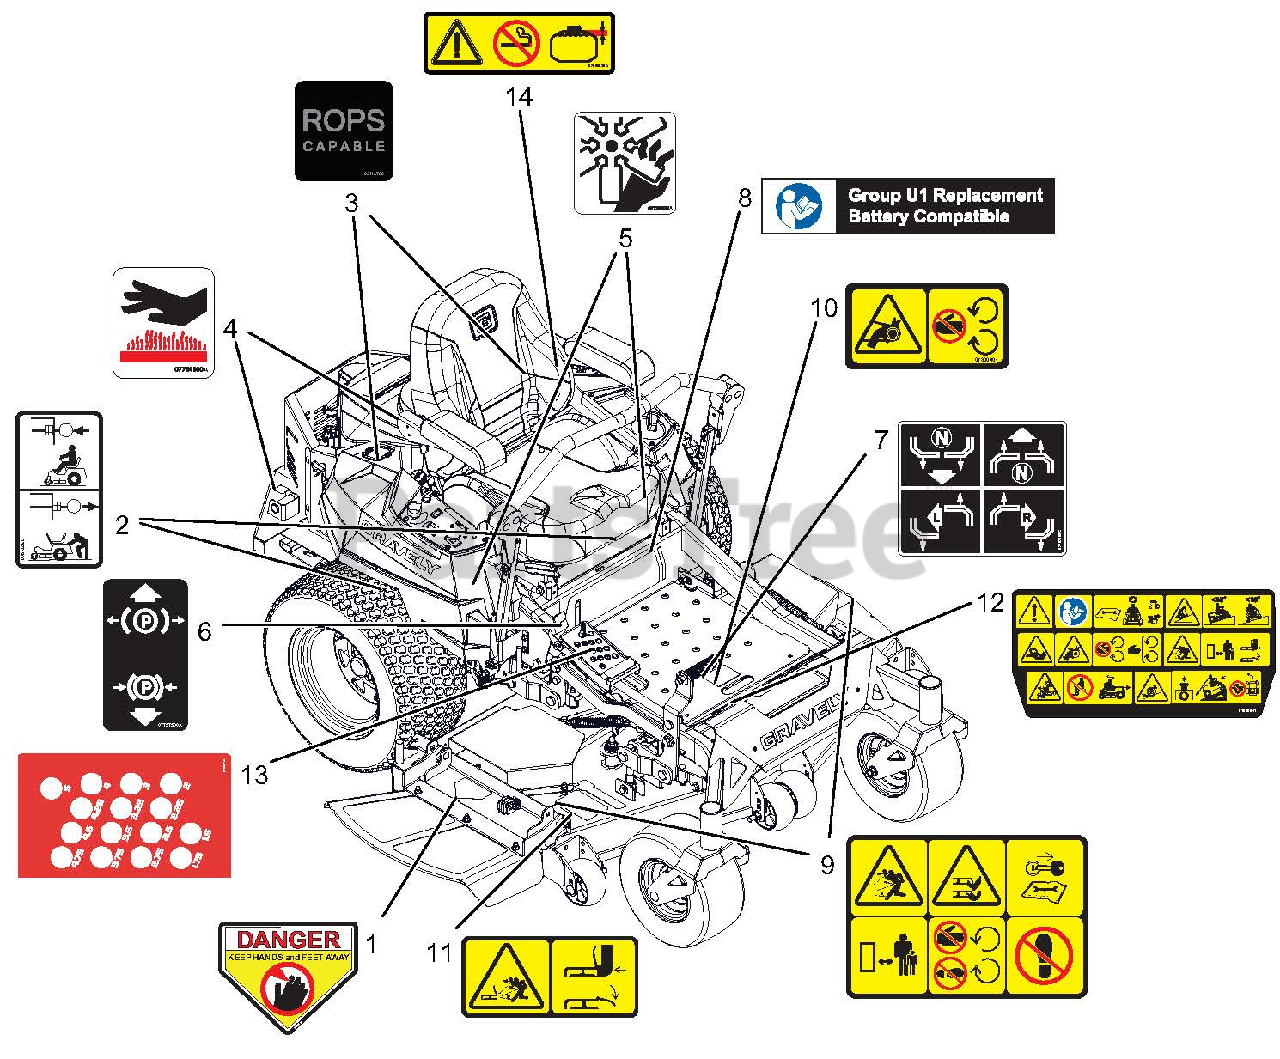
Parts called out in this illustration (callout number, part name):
1	DECAL, DANGER
2	DECAL, TRANSMISSION DISCONNECT
3	DECAL, ROPS LOCATION
4	DECAL, HOT SURFACE
5	DECAL, DANGER FAN
6	DECAL, PARKING BRAKE LEVER
7	DECAL, INSTRUCTIONAL-STEERING
8	DECAL, U1 BATTERY REPLACEMENT
9	DECAL, SAFETY - MOWER DECK
10	DECAL, SAFETY - GUARDING
11	DECAL, SAFETY - DECK GUARDING
12	DECAL, MAIN SAFETY
13	DECAL - HOC
14	DECAL, FUEL WARNING
